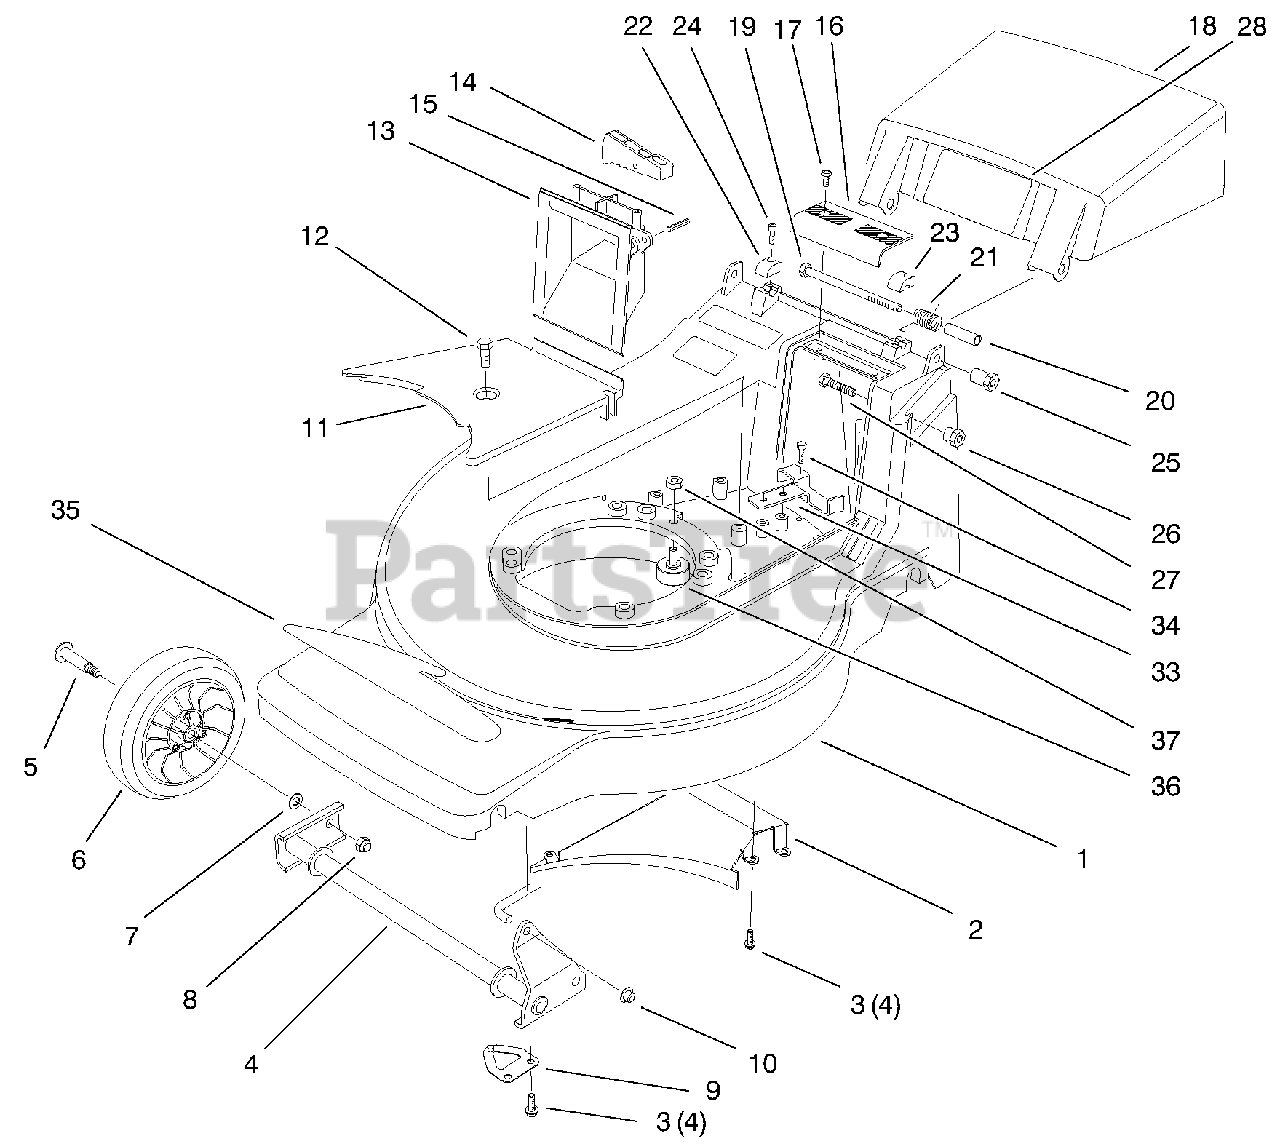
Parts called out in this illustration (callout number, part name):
1	Housing-Deck (Incl. Ref. # 35)
2	Ramp-Discharge
3	SCREW-HWH
4	PIVOT - FRONT WA
5	WHEEL BOLT
6	WHL & TIRE ASM 7"
8	Nut-Lock
9	SHAFT RETAINER ASM
10	PUSHNUT-CAP, WASHER
11	BELT COVER
12	SCREW-HWHTF
13	GRIP - LOWER
14	TRIGGER - HOC
15	PIN-SPIRAL
16	GRIP-UPPER
17	SCREW-PPH, PLASTITE
18	Door-Discharge (Incl. Ref. # 28)
19	5/16-18 X 4 CAPSCREW
20	DOOR SPACER
21	SPRING-DOOR
22	CAP-HINGE BOLT, RH
23	CAP-HINGE BOLT, LH
24	SCREW-HSH
25	48CM HANDLE SPACER
26	48CM HANDLE SPACER
27	5/16-18X1.50 HEX CAPSRW
28	DECAL-DANGER
33	REAR BELT GUIDE
34	SCREW-HWH
35	OBS DECAL - DECK 450VS
36	STUD-BEARING, BALL
37	NUT-LOCK, NI
